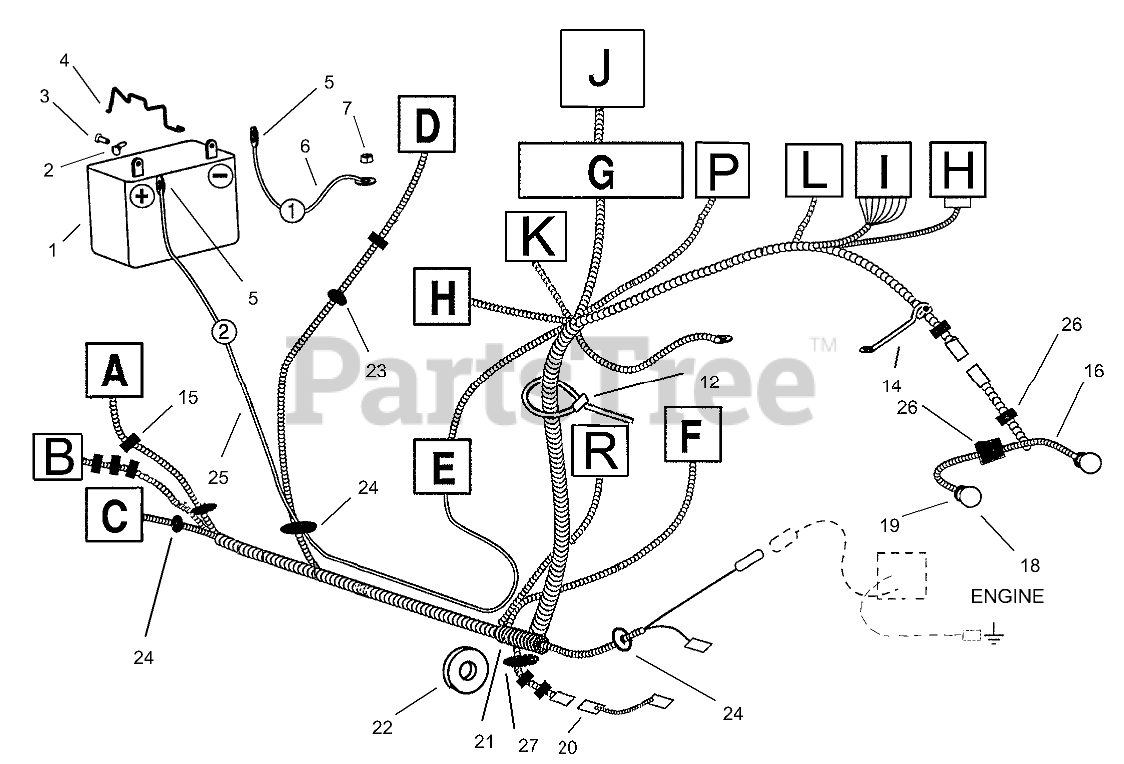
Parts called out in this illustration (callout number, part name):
1	BATTERY-12V
2	NUT-HHF
3	SCREW-HEX HD
4	CLAMP-BATTERY
5	BOOT-RUBBER
6	CABLE-BATTERY, Negative
7	NUT-LOCK, NI
12	TIE-CABLE
14	HOLDER-HARNESS, WIRING
15	CLIP-SNAP
16	HARNESS-WIRE, LIGHTS
18	BULB-LIGHT
19	SOCKET-LIGHT
20	HARNESS-CLUTCH
21	HARNESS-MAIN WIRING
23	BUSHING
24	BUSHING
25	CABLE-BATTERY POSITIVE
26	CLIP-NYLON
27	BUSHING
